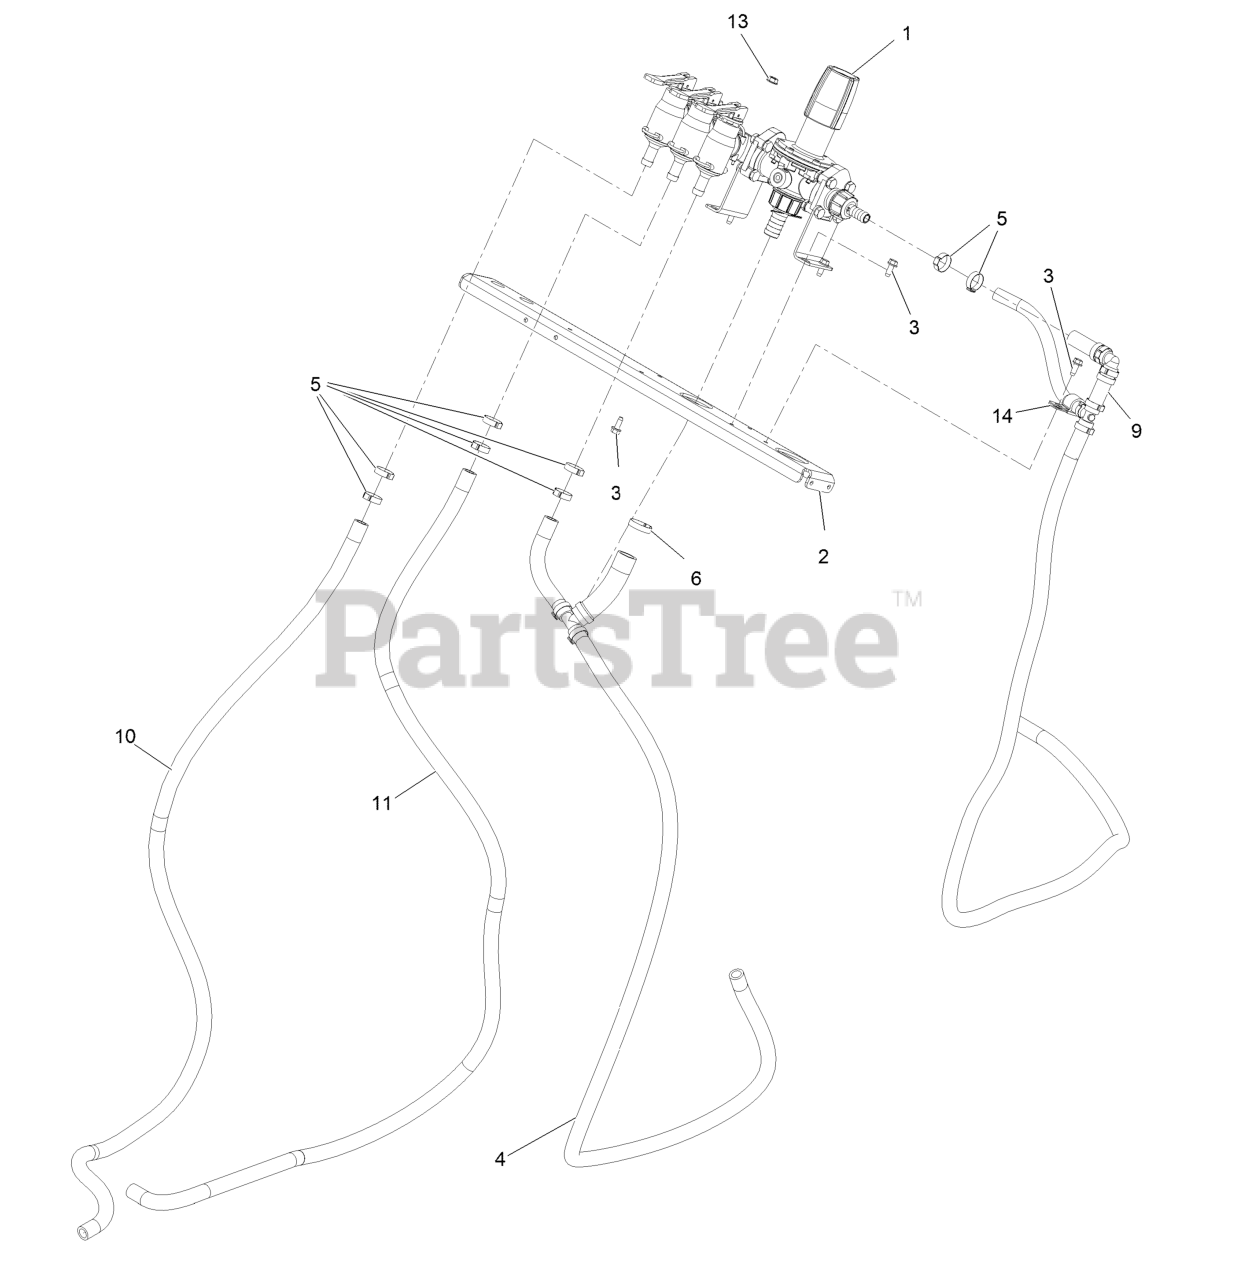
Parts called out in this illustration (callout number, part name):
1	Spray Manifold Assembly
2	Crossmember-Column
3	Screw-HWH
4	Hose ASM
9	Hose ASM
10	Hose-Water
11	Hose-Water
13	Nut-Hex Flg
14	Clip-Loom
